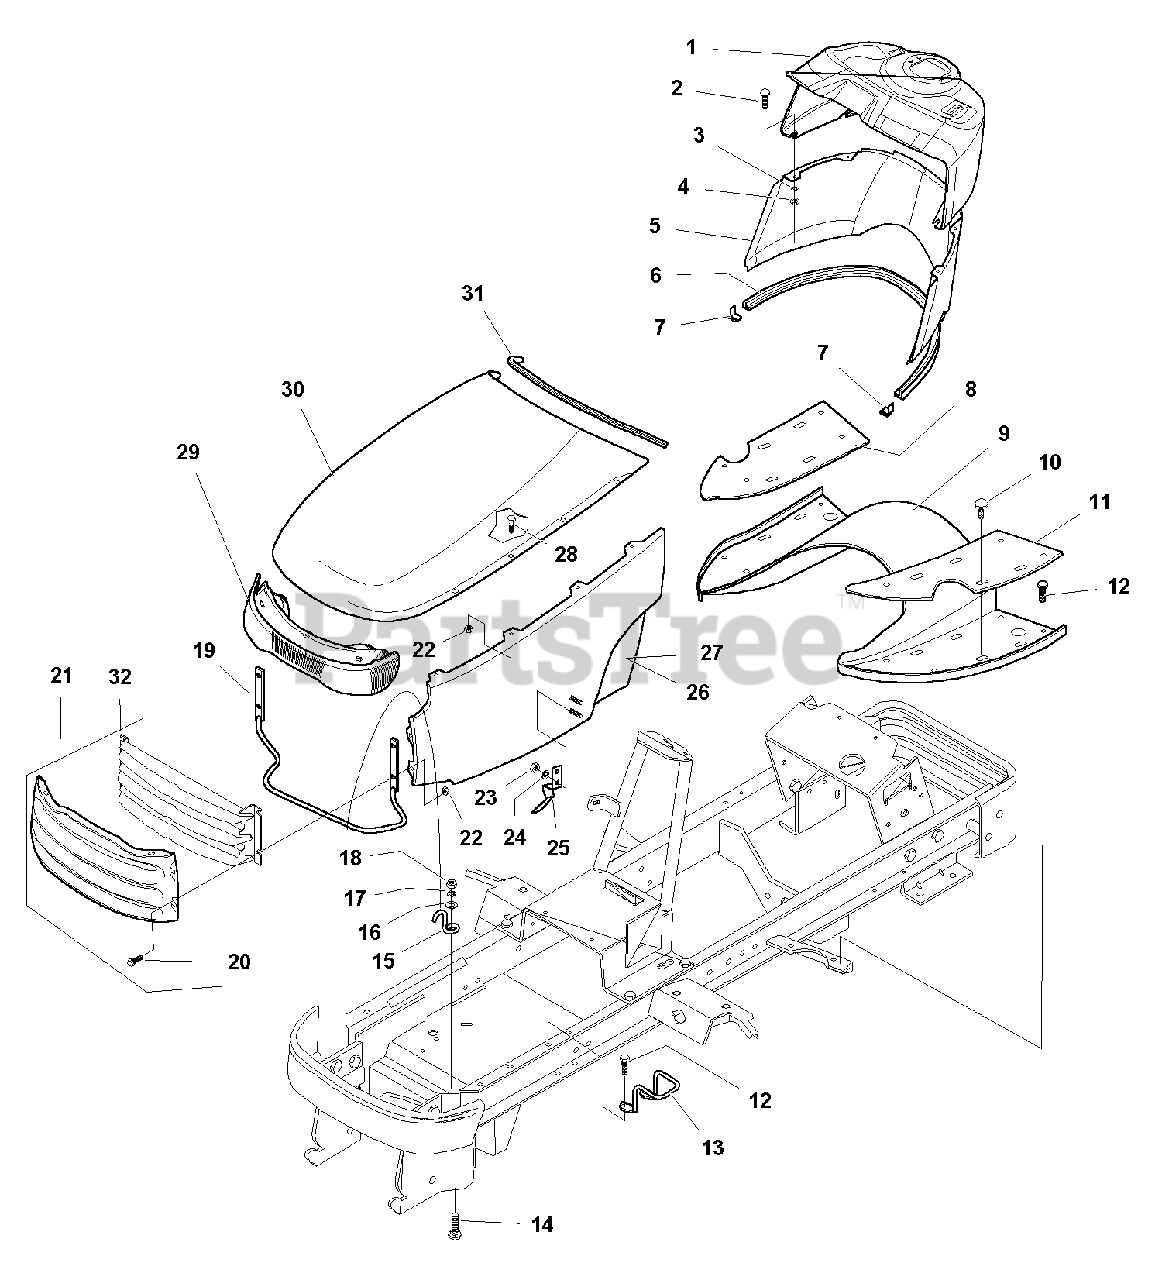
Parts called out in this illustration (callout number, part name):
1	DASH, Upper
2	CARRIAGE BOLT, 1/4-20 x 5/8
3	LOCKWASHER, 1/4
4	NUT, 1/4-20
5	DASH, Lower
6	EDGING, Dash
8	PAD, Footrest, RH
10	CLIP, Footpad
11	PAD, Footrest, LH
12	CAPSCREW, Taptite, 1/4-20 x 1/2
13	ROD, Hood Latch
14	CARRIAGE BOLT, 5/16-18 x 1
15	ROD, Hood Latch Pivot
16	WASHER, Flat
17	LOCKWASHER, 5/16
18	NUT, Hex, 5/16-18
19	ROD, Hood Hinge
20	CAPSCREW, Hex Head Whizlock, 1/4-20 x 1
21	GRILL ASSEMBLY (Orange)
21	GRILL ASSEMBLY (Red)
22	NUT, Hex Whizlock, 1/4-20
23	NUT, Nylock, #10-24
25	CLIP, Hood Latch
26	SIDE PANEL, LH (Orange)
26	SIDE PANEL, LH (Red)
27	SIDE PANEL, RH (Orange)
27	SIDE PANEL, RH (Red)
28	CAPSCREW, Hex Head Whizlock, 1/4-20 x 5/8
29	HEADLIGHT BEZEL
30	HOOD (Orange)
31	EDGING, Hood
